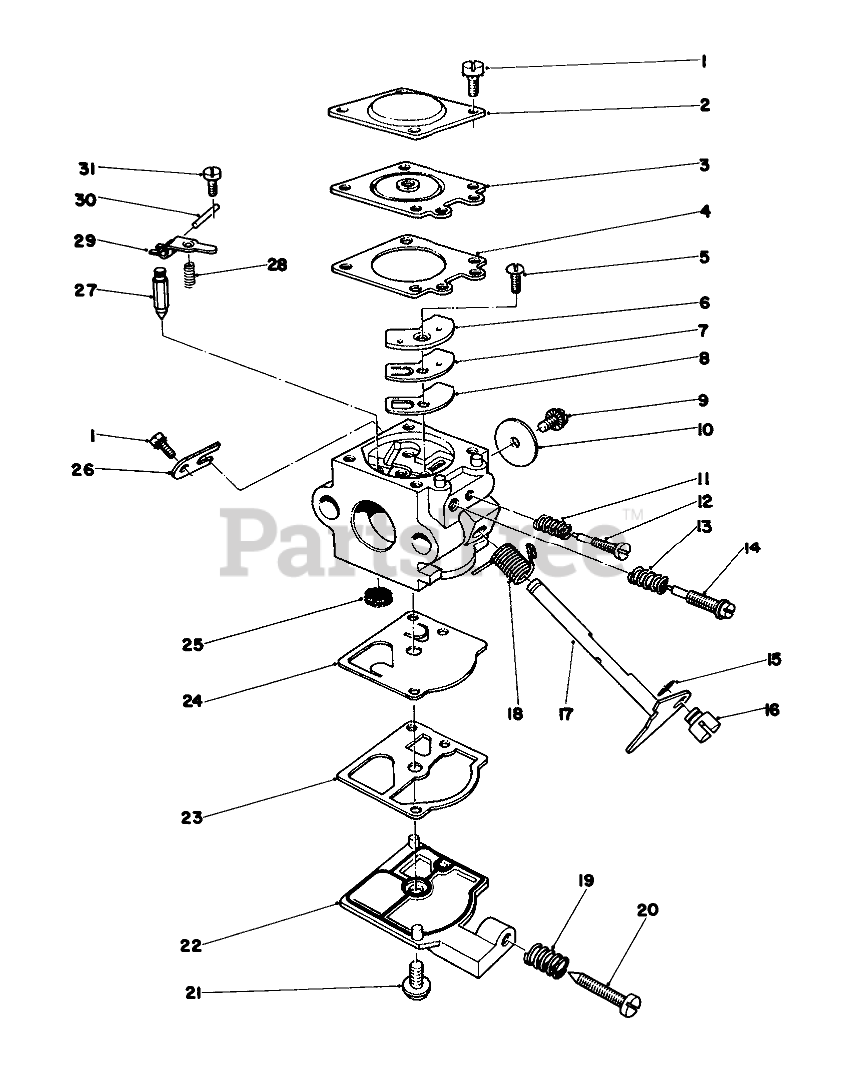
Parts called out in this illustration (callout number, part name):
1	Screw
2	Cover, Diaphragm
3	METERING DIAPHRAGM
4	Gasket, Diaphragm
5	Screw-Circuit Plate
6	Plate, Circuit
7	Diaphragm Circuit Plate
8	Gasket-Circuit Plate
9	Screw
10	Valve, Throttle
11	Spring, Needle
12	Idle Needle
13	Spring, HS Needle
14	Needle, HS
16	Swivel
17	THROTTLE SHAFT ASM
18	Spring-Throttle Lever
19	Spring, Idle Screw
20	Screw, Idle Adjust
21	Screw
22	Cover, Fuel Pump
23	PUMP GASKET
24	Diaphragm Fuel Pump
25	Screen Inlet
26	Clip Throttle Shaft
27	INLET NEEDLE VALVE
28	Spring, Lever
29	Lever Metering
30	Metering Lever Pin
31	Screw-Metering Pin
